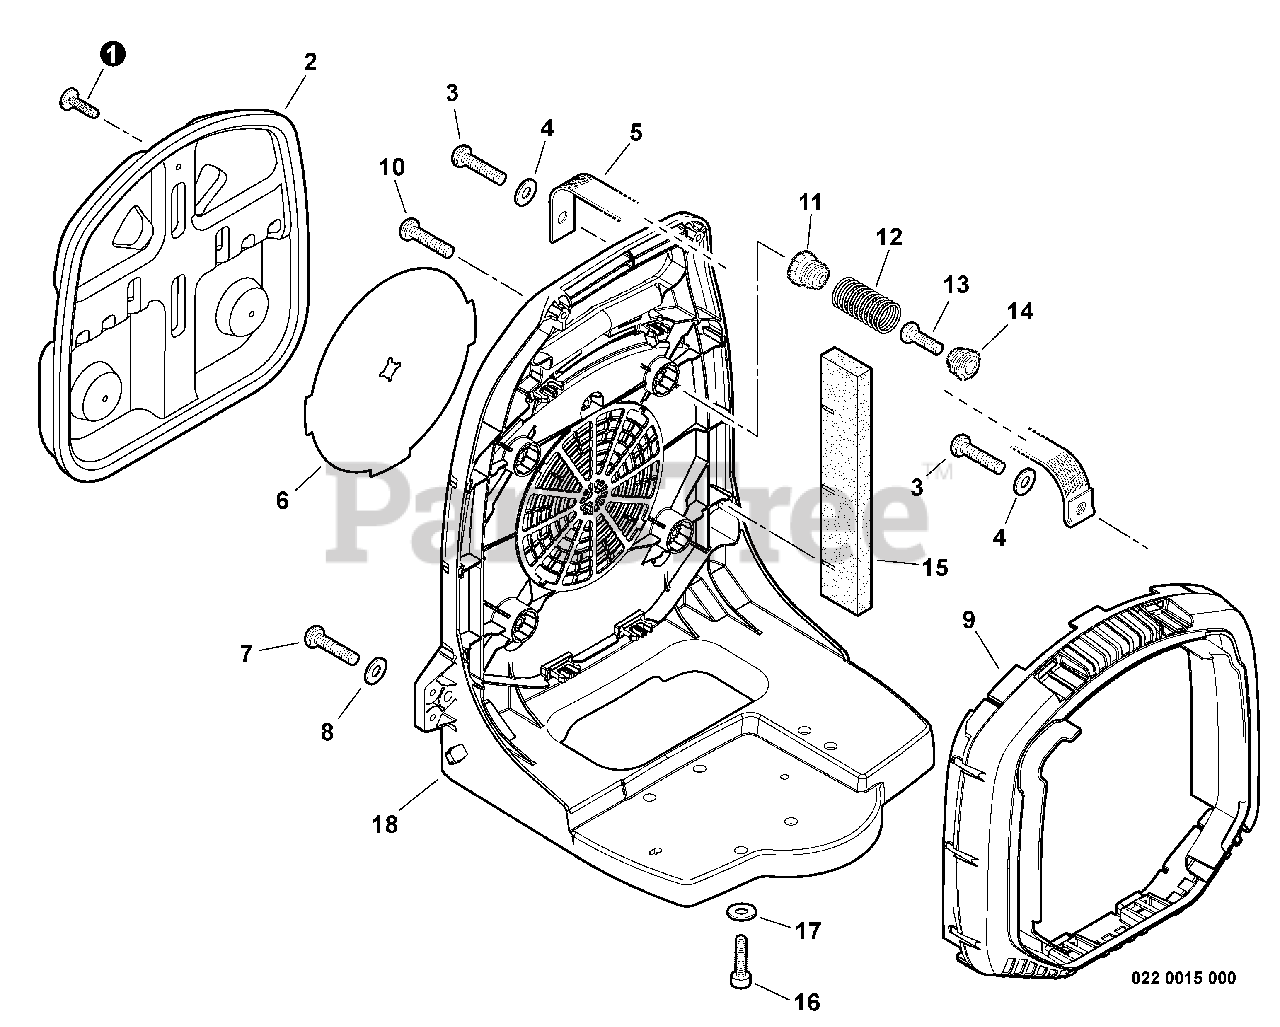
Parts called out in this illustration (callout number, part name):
2	CUSHION, BACKPACK
3	BOLT, TORX 5×20
4	WASHER 5.5×16×2T
5	STRAP, SAFETY 1.2×100
6	INSERT, COLD WEATHER
7	BOLT, TORX 5×20
8	WASHER 5.5×16×2T
9	GUARD, DEBRIS
10	BOLT, TORX 5×20
11	HOLDER, SPRING
12	SPRING, COMPRESSION
13	BOLT, TORX 5×16
14	HOLDER, SPRING
15	PAD, FOAM
16	BOLT, TORX 5×25
17	WASHER 5.5×16×2T
18	FRAME, BACKPACK
